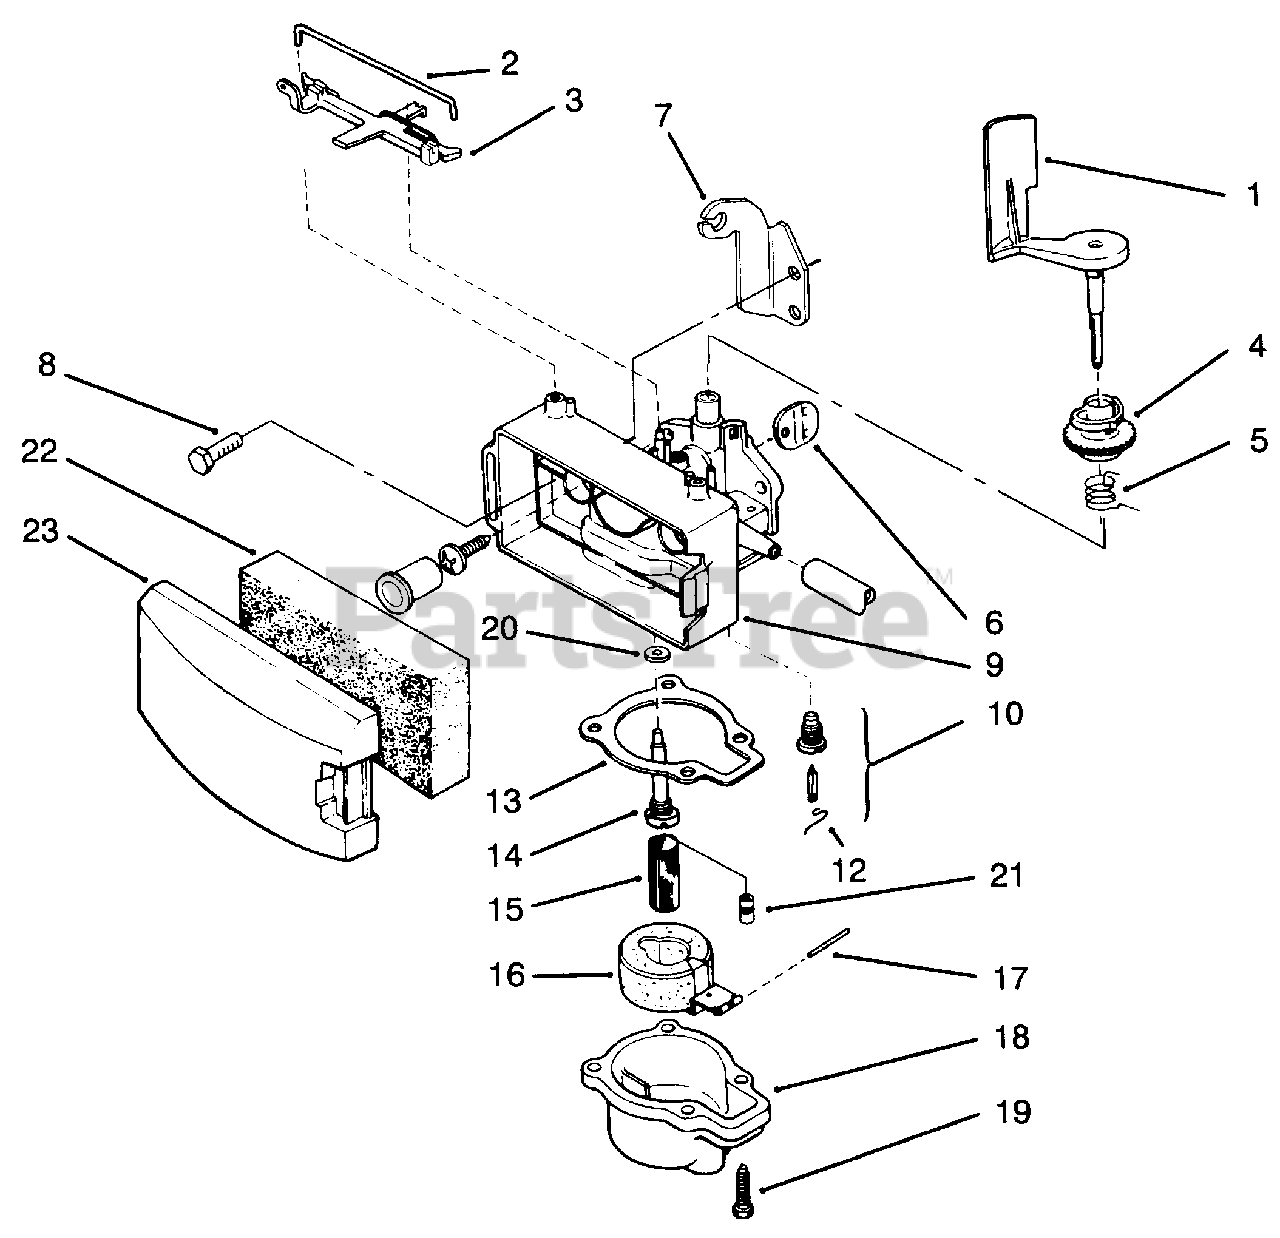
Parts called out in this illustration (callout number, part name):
1	Air Vane & Shaft
2	Retainer-Speed Control
3	Lever-Speed Adjust
4	Collar-Air Vane
5	Spring-Governor
6	Disc-Throttle
7	Bracket-Throttle Control
9	Carburetor Body
10	Kit-Float Valve, Body & Seat (Incl. Ref.#12)
12	Spring
13	Gasket
15	Filter-Fuel
16	Float & Arm Assembly
18	Float Chamber
21	Main Jet
22	Filter
23	Cover
